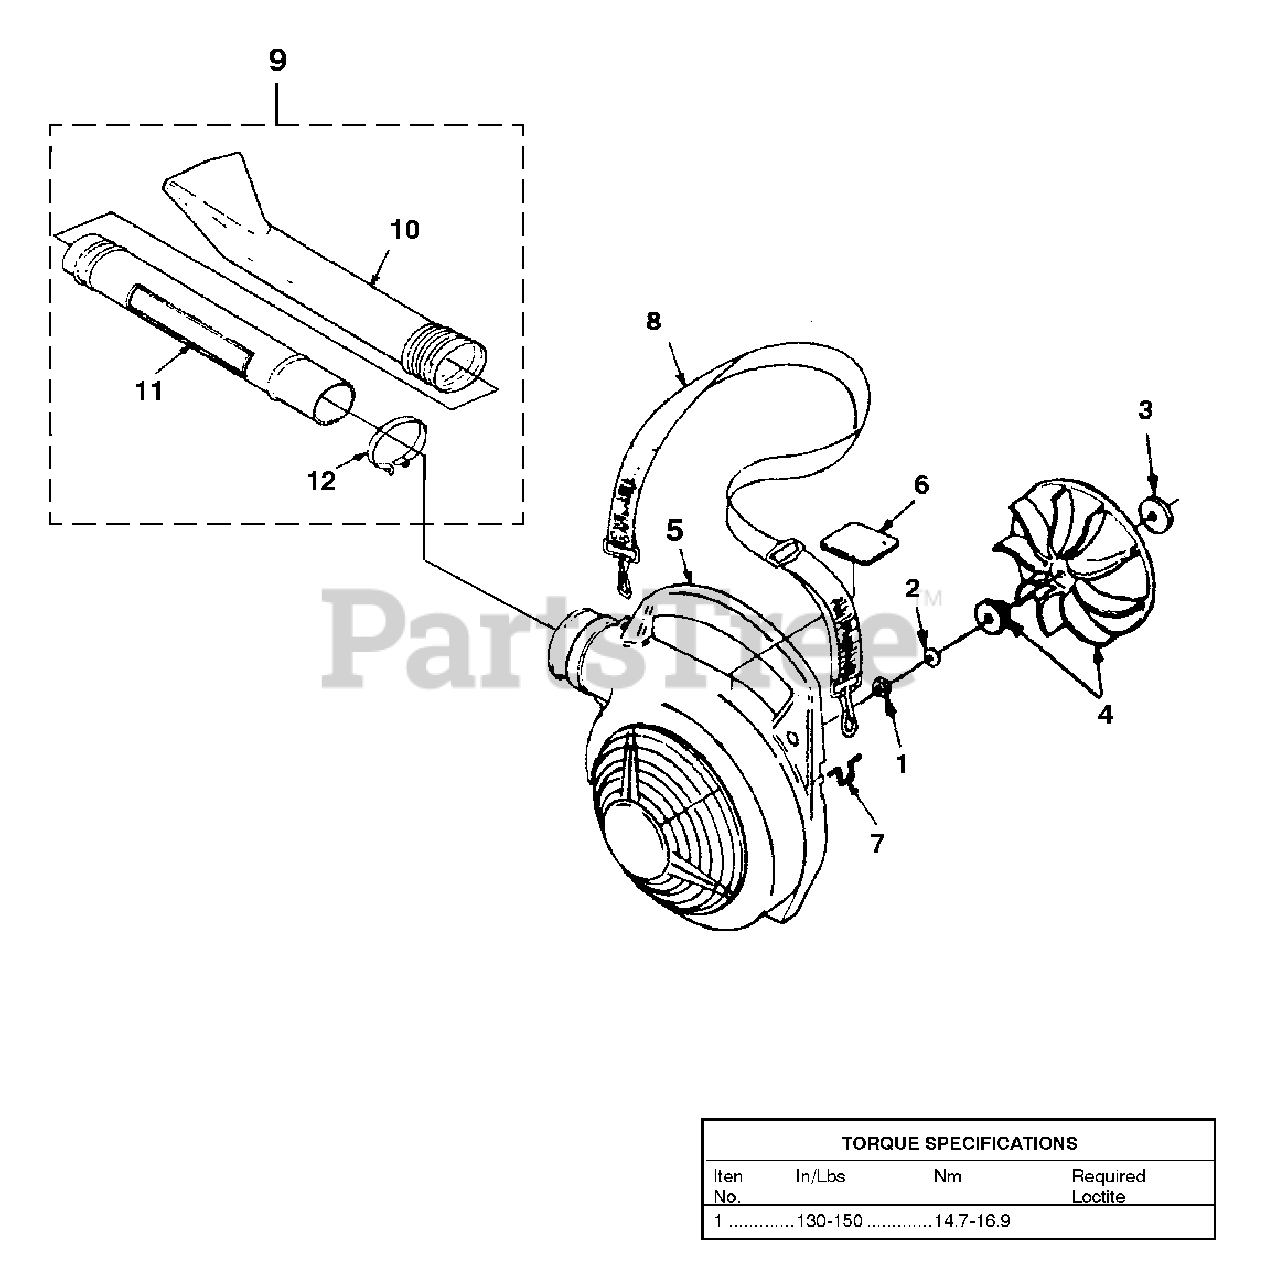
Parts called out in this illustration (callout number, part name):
1	NUT-Hex (3/8-24)
2	WASHER-Bellville (3/8")
3	WASHER-Flat
4	BLOWER FAN KIT
5	VOLUTE HOUSING (Outer)
6	DECAL-Warning
7	LOOP-Wire
8	SHOULDER STRAP
9	BLOWER TUBE KIT
10	NOZZLE-Sweeper
12	CLAMP w/Fasteners
